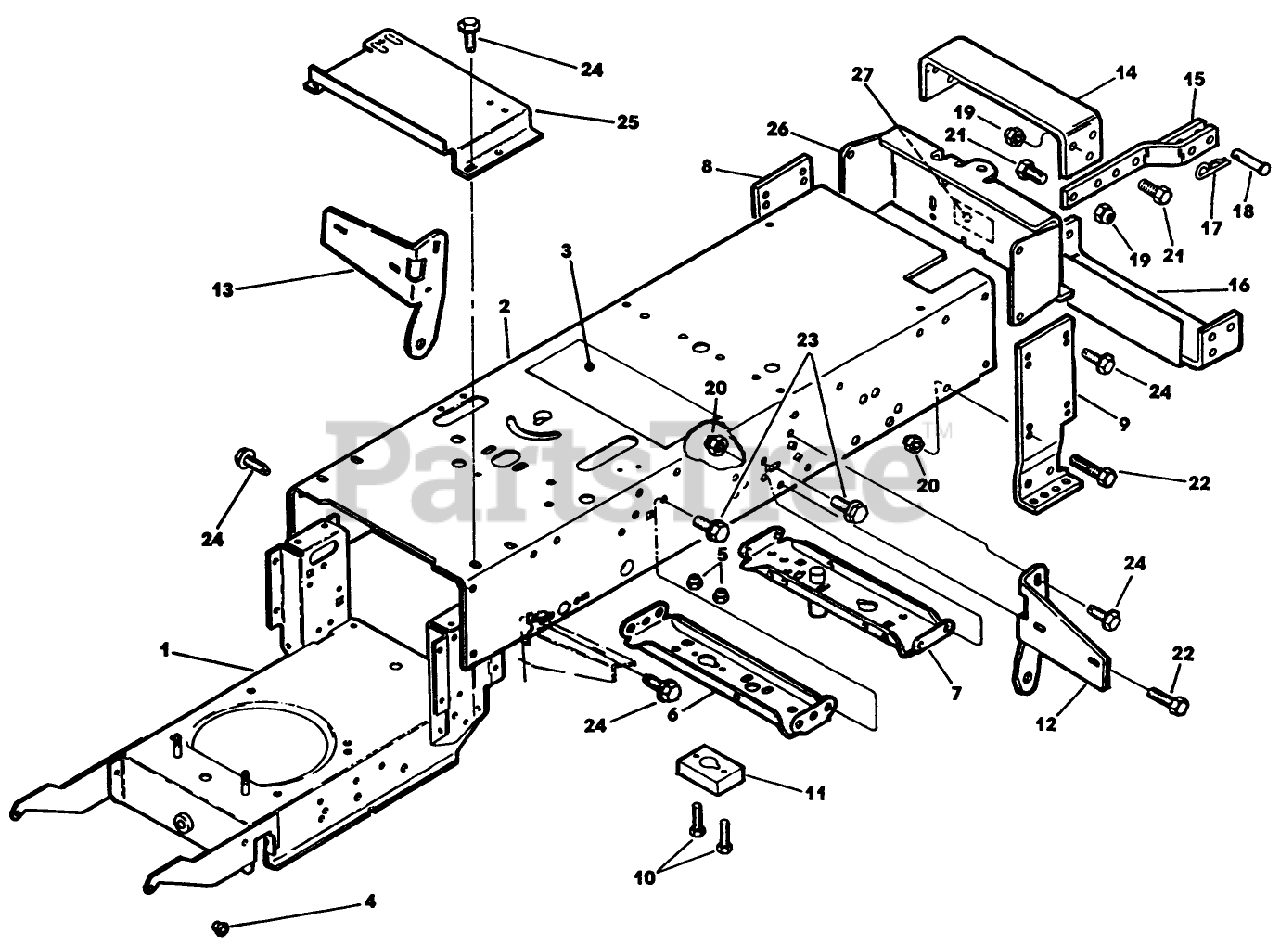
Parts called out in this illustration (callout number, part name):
4	BEARING-NYLINER
5	NUT-LOCK, CONE
6	SUPPORT *B
10	SCREW
11	BRACKET-SUPPORT *B
13	SUPPORT - RH
17	PIN - SPRING CLIP
19	NUT-LOCKING
20	NUT
22	SCREW
25	SUPPORT, BATTERY *B
